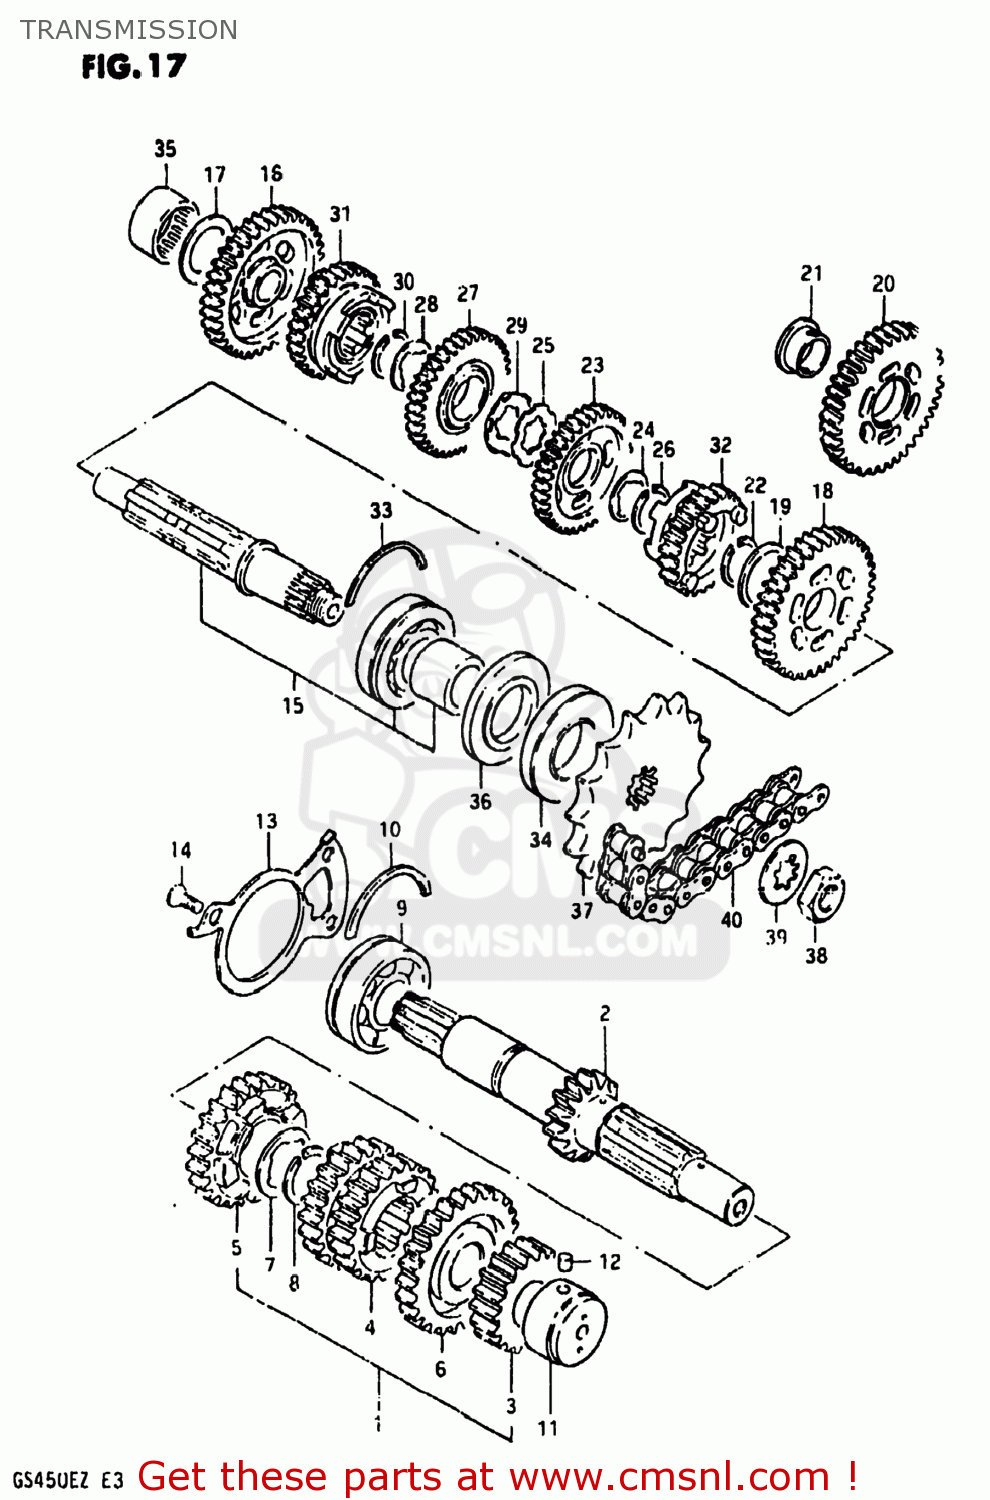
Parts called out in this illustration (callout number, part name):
1	SHAFT,COUNTER
2	SHAFT,COUNTER
3	GEAR,2ND DRIVE(NT:18)
4	GEAR,THIRD DRIVE
5	GEAR,FIFTH DRIVE
6	GEAR,SIXTH DRIVE
7	WASHER
8	CIRCLIP
9	BEARING(25X62X17)
10	C-RING
11	ROLLER BEARING (20X34X2
12	PIN
13	PLATE,COUNTERSHAFT BEARING
14	SCREW
15	SHAFT,DRIVE
16	GEAR,FIRST DRIVEN
17	WASHER
18	GEAR,SECOND DRIVEN
19	WASHER
20	GEAR,SECOND DRIVEN
21	BUSHING
22	CIRCLIP
23	GEAR,THIRD DRIVEN
24	WASHER,LOCK
25	WASHER,LOCK
26	CIRCLIP
27	GEAR,FOURTH DRIVEN
28	WASHER,LOCK
29	WASHER
30	CIRCLIP
31	GEAR,5TH DRIVEN(NT:25)
32	GEAR,SIXTH DRIVEN
33	C-RING
34	SEAL,OIL(32X64X8)
35	ROLLER BEARING (20X34X1
36	SEAL,OIL(32X62X5.5)
37	SPROCKET,ENGINE(NT:16)
38	NUT
39	WASHER
40	CHAIN ASSEMBLY,DRIVE
